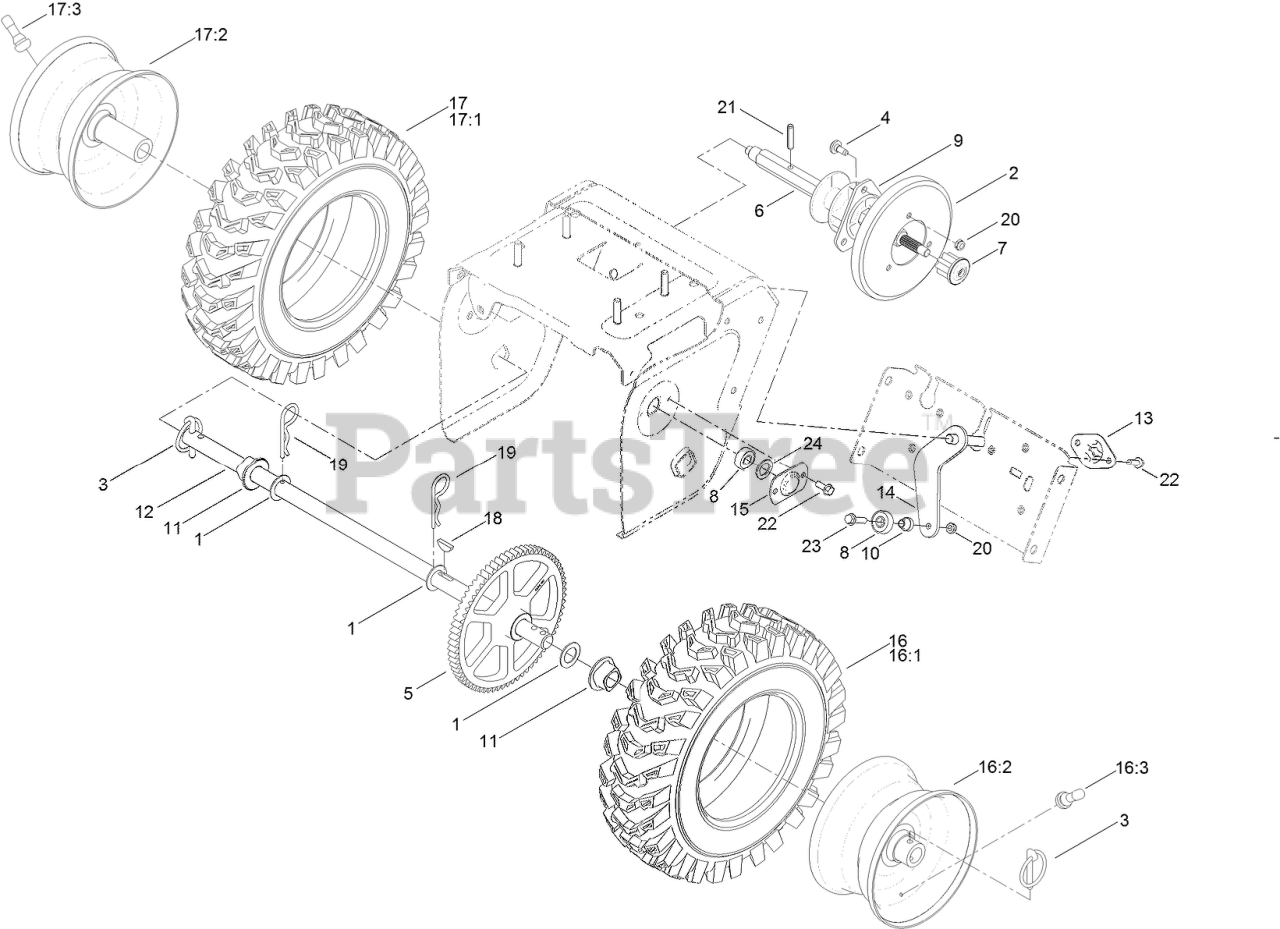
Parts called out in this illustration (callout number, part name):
1	WASHER-THRUST
2	WHEEL-FRICTION
3	KLIK PIN ASM
4	SCREW-SHOULDER
5	GEAR-AXLE
6	SHAFT-HEX
7	GEAR-PINION, 8 TOOTH
8	BEARING-BALL
9	TRUNNION
10	SPACER-PLATE, SHIFT
11	BUSHING-AXLE
13	RETAINER-PLATE, SHIFT
14	SHIFT PLATE ASM
15	RETAINER-BEARING
16	LH WHEEL AND TIRE ASM
16:1	RIM-TIRE
16:3	STEM-VALVE
17	RH WHEEL AND TIRE ASM
17:1	RIM-TIRE
17:3	STEM-VALVE
18	KEY-WOODRUFF
19	PIN-HAIR
20	NUT-LOCK, NI
21	PIN-ROLL, SLOTTED
22	SCREW-HWH
23	SCREW-HWHTF
24	WASHER-RUBBER
